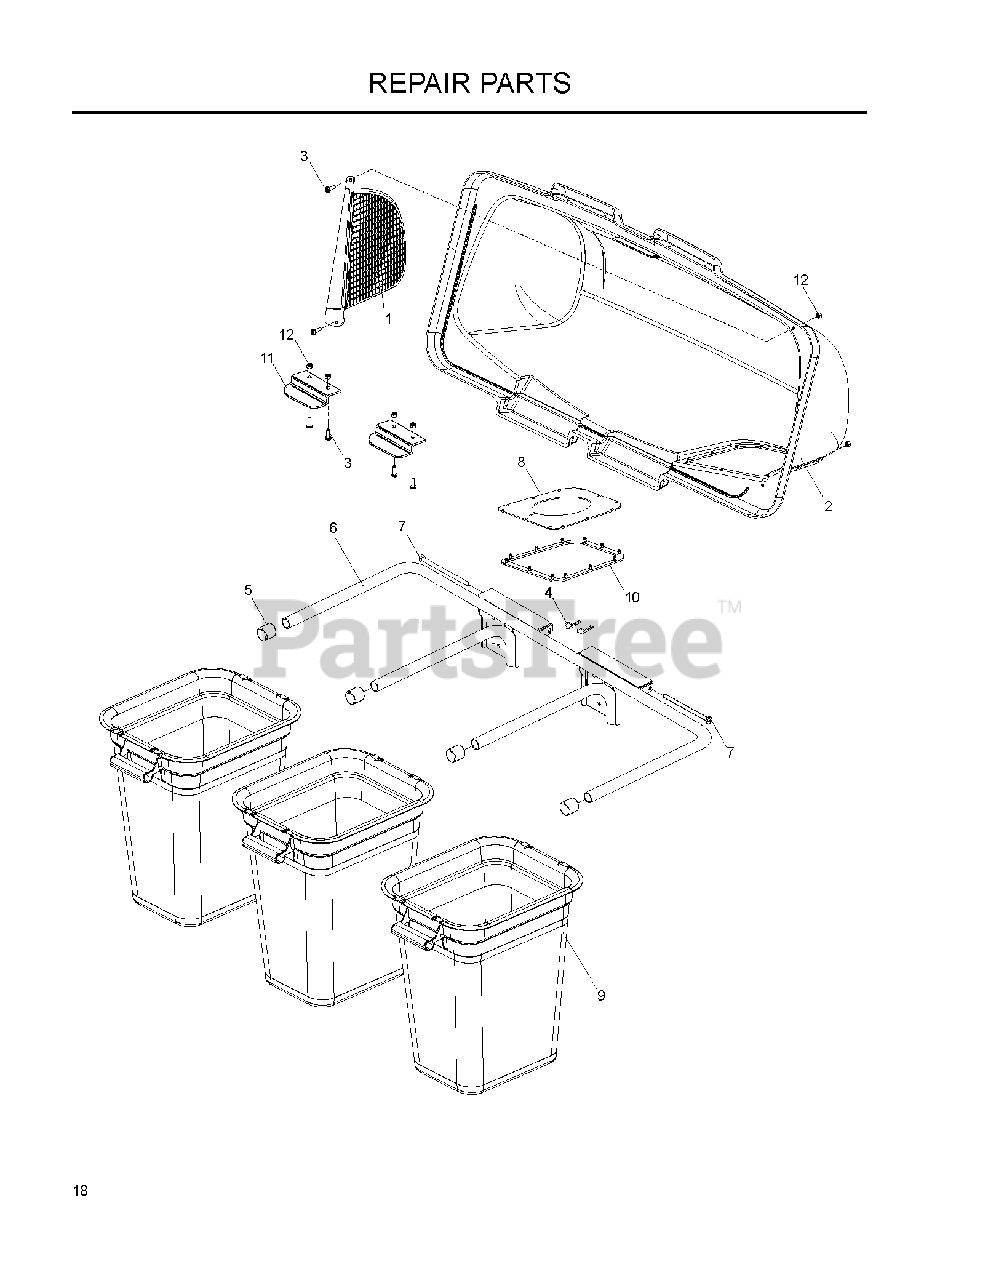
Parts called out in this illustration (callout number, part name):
1	SCREEN.COVER.BAGGER
2	COVER.ASM.3BIN.GENERIC.
3	SCREW #10-24 X 5/8
4	RETAINER SPRING
5	TUBING PLUG
6	BAGGER.ASM.FRAME.3BIN.BLACK
7	BAGGER.HINGE.PIN
8	SEAL.BAGGER.TOP.3-BIN.BLK
9	CONTAINER BAG, SOFT
10	GASKET.COVER.BAGGER
11	LATCH CER38
12	NUT 10-24 NYLOC
